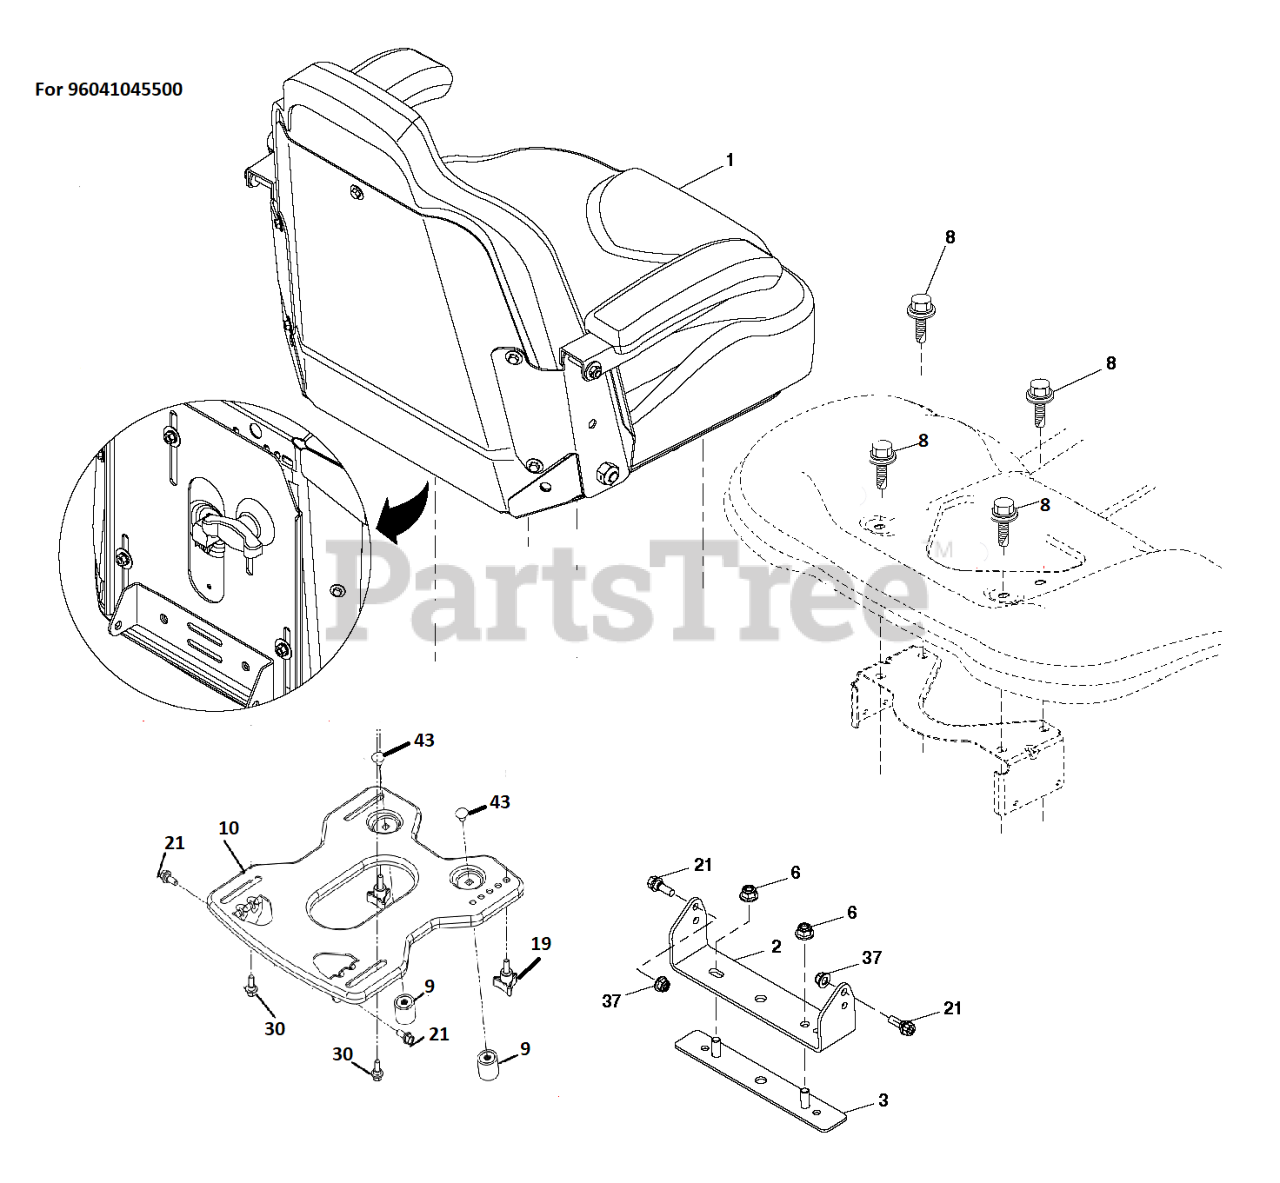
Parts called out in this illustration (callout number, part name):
1	18 IN MILSCO SEAT
3	STRAP
8	BOLT.5/16-18UNCX3/4 W/SEMS.BLK
10	BRACKET SEAT PAN
19	GSPW Knobs
37	NUT HEXAGON FLANGE 5/16-18 ST
